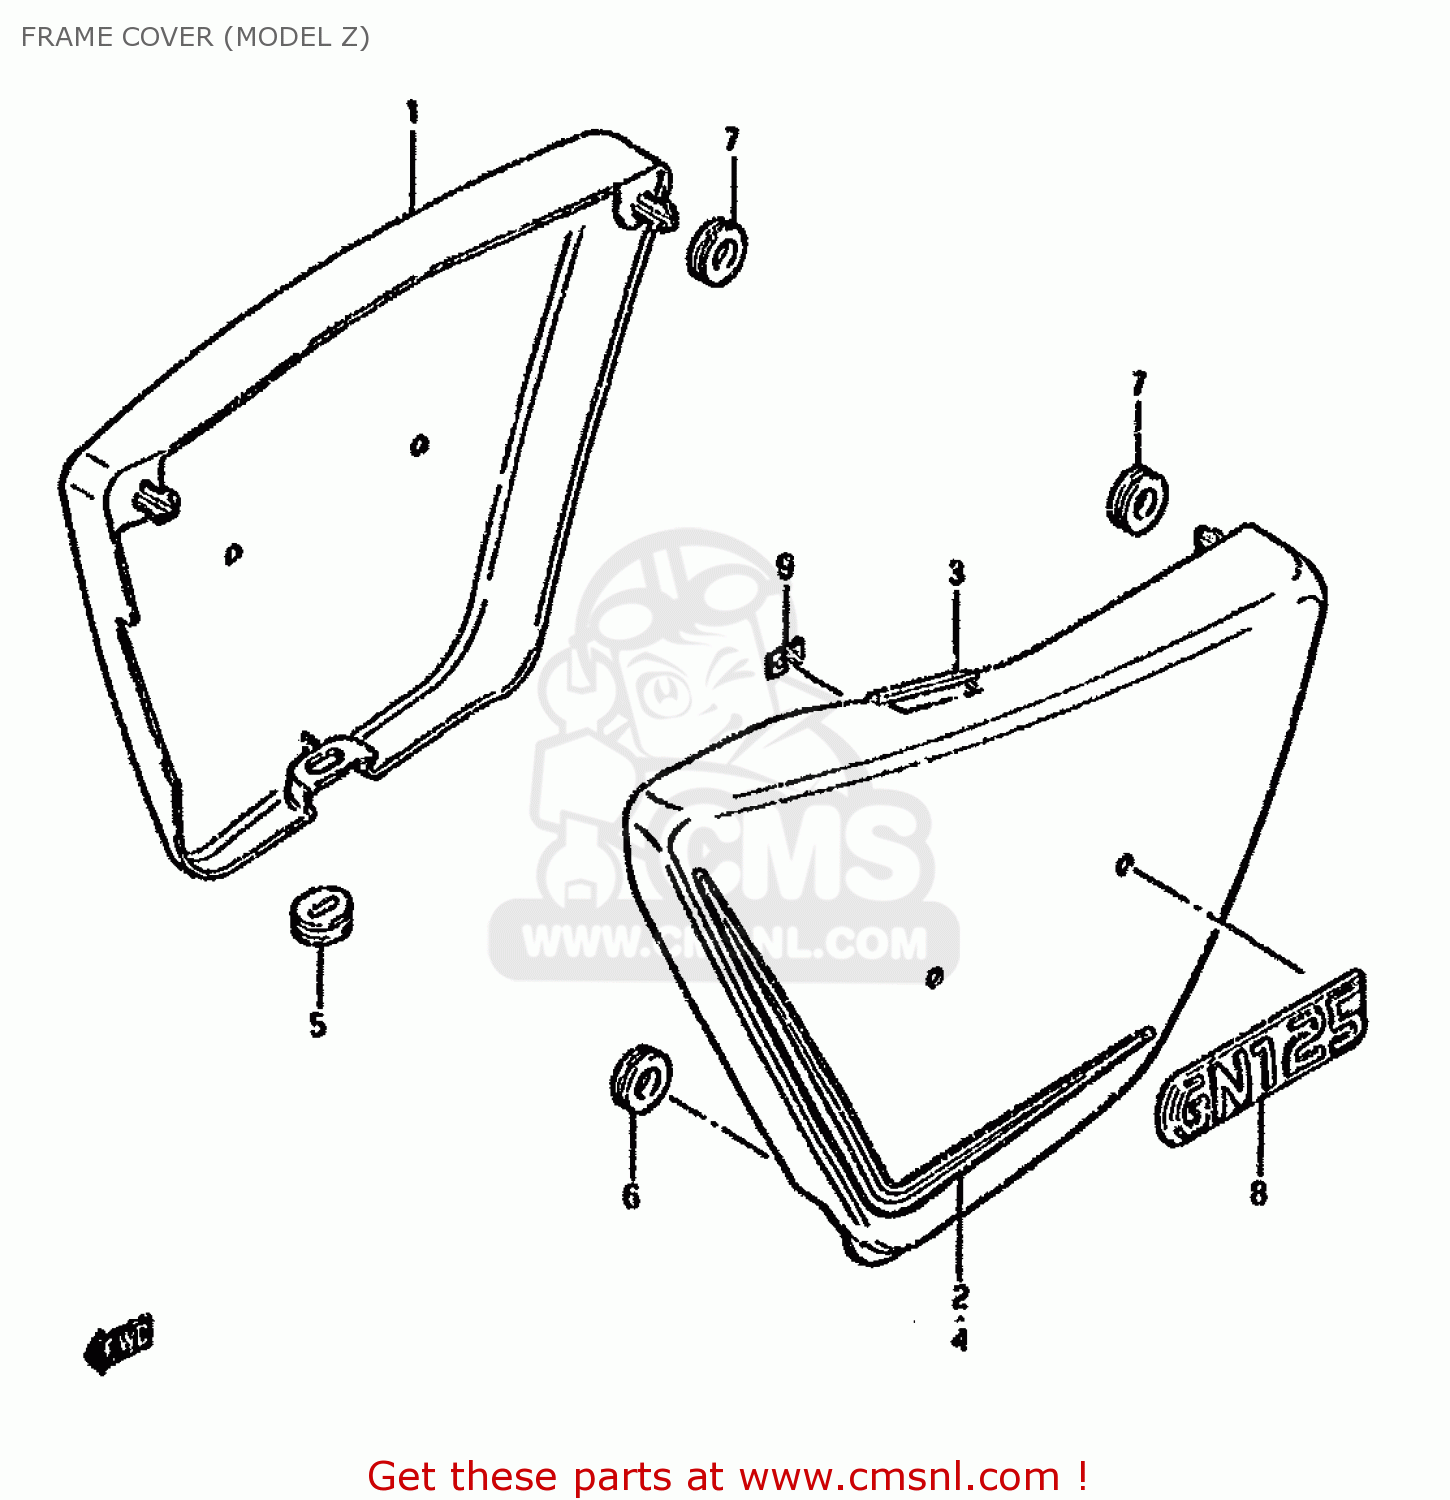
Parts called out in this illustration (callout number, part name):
1	COVER,FRAME,RIGHT
2	TAPE,FRAME COVER
3	COVER,FRAME,LEFT
4	TAPE,FRAME COVER
5	CUSHION
6	CUSHION
7	CUSHION
8	EMBLEM,FRAME COVER
9	NUT
